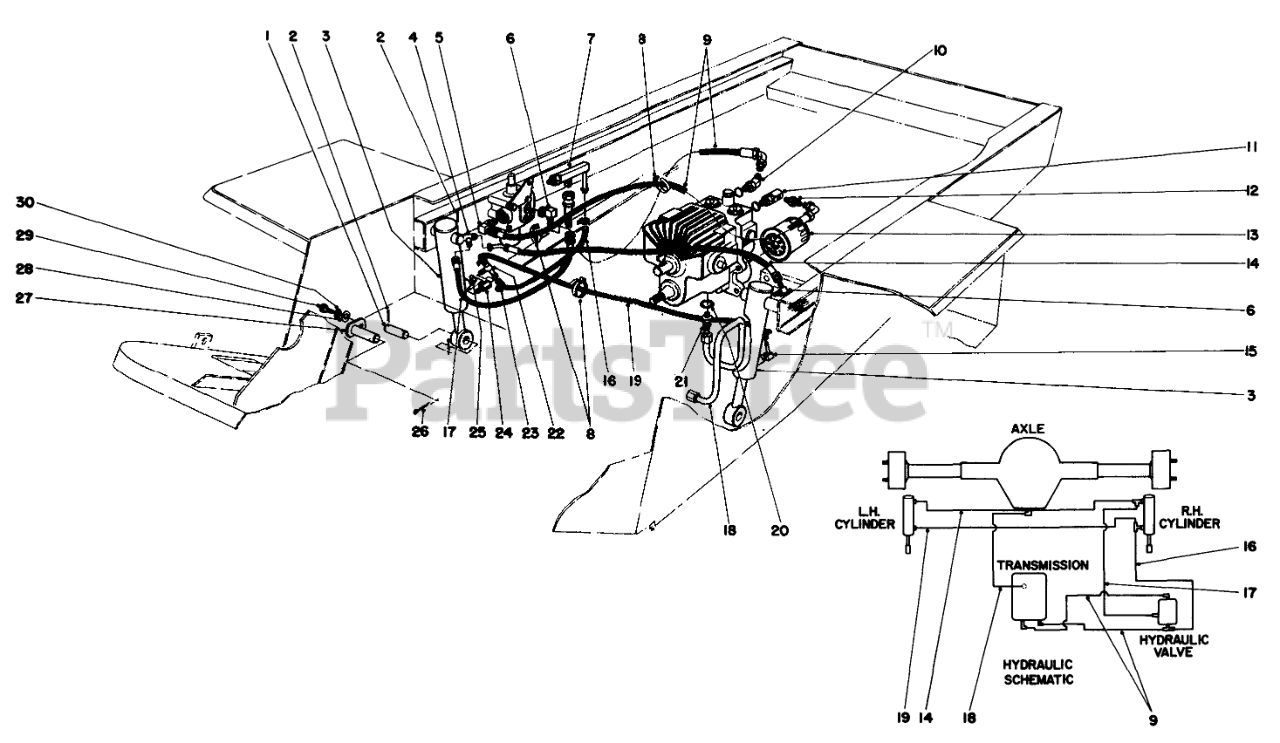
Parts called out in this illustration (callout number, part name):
1	PIN-CYLINDER
2	PIN-COTTER
3	Lift Cylinder
4	FITTING-TEE, ADJ.
5	FITTING-ELBOW, 90 DEG
6	FITTING-ELBOW, 90
7	Fitting Assembly
8	TIE-CABLE
9	TRANS-VALVE HOSE
10	FITTING-ELBOW, 45 DEG
11	SPECIAL FITTING PP
12	Adapter
13	FILTER-OIL, TRANSMISSION
14	RH CYL HOSE
15	STEM-HOSE
17	RH HOSE
18	HYORAULIC TUBE
19	HOSE-FUEL
20	O-RING
21	Fitting (Incl. Ref. #20)
22	MALE TEE FITTING
23	CLAMP-HOSE
24	CONN FITTING
25	O-RING
26	PIN-COTTER
27	Pin-Pivot
28	WASHER-FLAT
29	SCREW-HH
30	WASHER-LOCK
